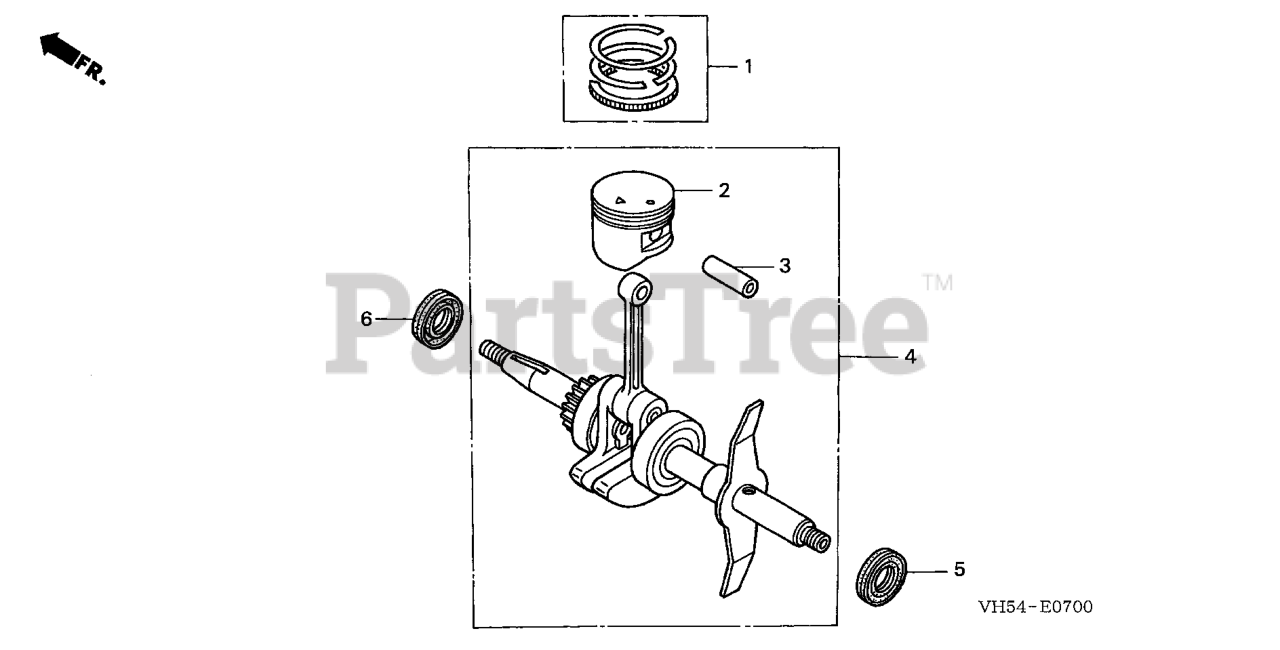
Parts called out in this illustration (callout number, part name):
1	RING SET, PISTON (RIKEN)
2	PISTON
3	PIN, PISTON
4	CRANKSHAFT COMP.
5	OIL SEAL (12X25X6)
6	OIL SEAL (15X25X6)
